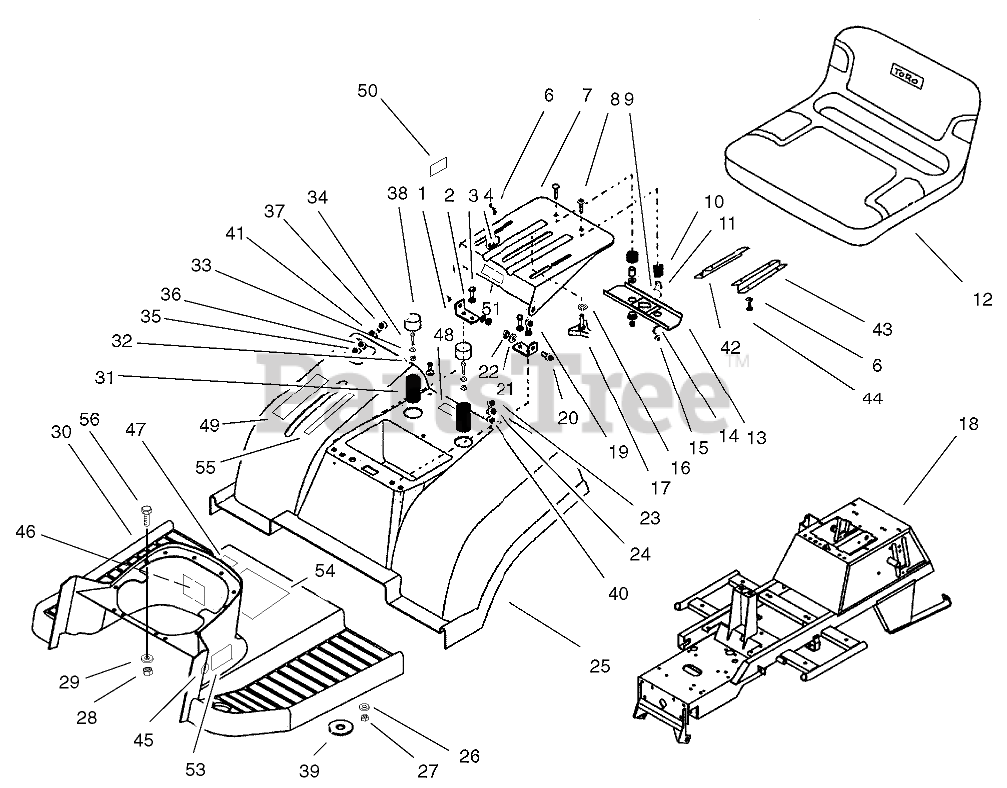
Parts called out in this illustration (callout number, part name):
1	BRACKET-SUPPORT, SEAT
2	WASHER-SPRING
3	SCREW-HH
4	BOLT-HEX
6	WASHER-SPRING
7	SUPPORT-SEAT
8	BOLT-CARRIAGE
9	WASHER-FLAT
10	SPRING-SEAT
11	SPACER-SPLIT
12	SEAT-V-511
13	BRACKET
14	BUSHING
15	NUT-LOCK
16	WASHER-SPRING
17	KNOB-ADJUSTMENT
18	FRAME-CHASSIS
19	SCREW-HH
20	SCREW-SUPPORT, SEAT
21	WASHER-PLAIN
22	NUT-LOCK, NI
23	SCREW-HSFH
24	WASHER-FINISH
25	FENDER
26	WASHER-FLAT
27	NUT-LOCK, NI
28	NUT-LOCK
29	WASHER-FLAT
30	FOOTREST ASM
31	SPRING-SEAT
32	NUT-LOCK, NI
33	WASHER-PLAIN
34	SCREW-HH
35	NUT-LOCK
36	WASHER-FLAT
37	BOLT-CARRIAGE
38	CAP-HUB
39	WASHER-RUBBER
40	WASHER-RUBBER
41	WASHER-RUBBER
42	BRACKET-RIGHT SEAT
43	BRACKET-LEFT SEAT
44	Screw
45	DECAL-BRAKE, PARKING
46	DECAL-STARTING
47	DECAL-OPERATION, HYDRO
48	DECAL-BAG TO FRAME
49	DECAL-HOC, RH
50	DECAL-SWITCH
51	DECAL-DANGER
53	DECAL - TOWER 190DH
54	DECAL-INSTRUCTION
55	DECAL-HOC, LH
56	SCREW-HH
